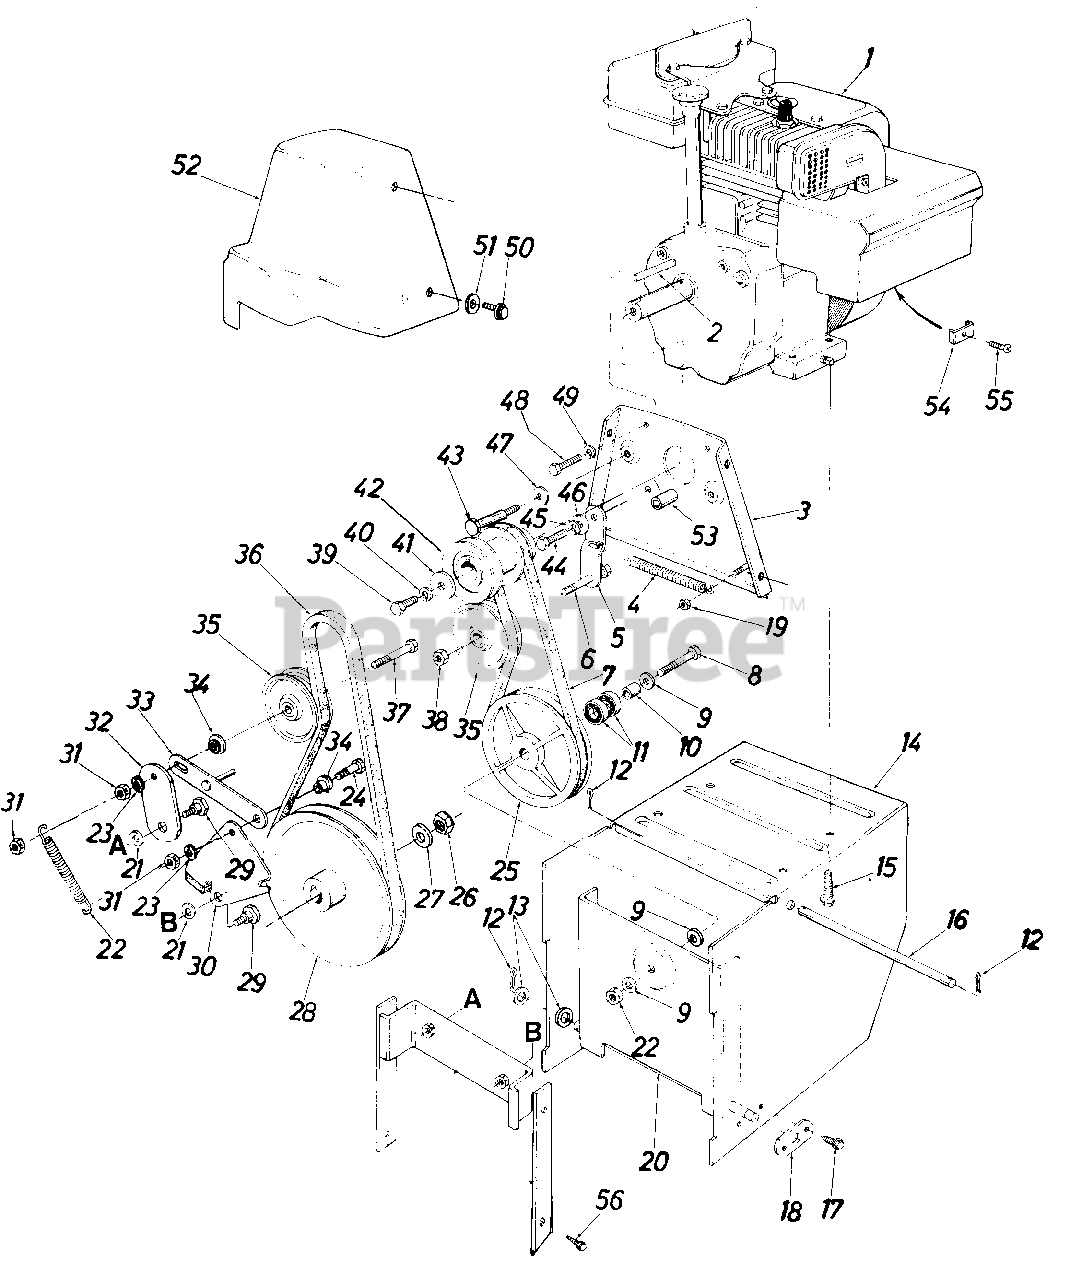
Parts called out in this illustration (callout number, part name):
1	Engine
2	Sq. Key 3/16" x 1.50" Lg.
3	Engine Plate Ass'y.
4	Extension Spring .50" O.D. x 3.97" Lg.
5	Drive Clutch Idler Brkt.
6	Hex Bolt 3/8-24 x 1.25" Lg.
7	V-Belt 3/8" x 29.0" Lg.
8	Hex Bolt 3/8-24 x 1.50" Lg.
9	Bell-Wash. .40" I.D. x .88" O.D. x .06
10	Spacer .38" I.D. x .62" O.D. x.75" Lg.
11	Ball Brg. .62" I.D. x 1.38" O.D. x .44
12	Cotter Pin 3/32" Dia. x .75" Lg.
13	Fl-Wash. .53" I.D. x 1.00" O.D. x .125
14	Frame Ass'y.
15	Hex Wash. Hd. Self-Tap Scr. 3/8-16 x 1.25" Lg.
16	Shaft .50" Dia. x 9.50" Lg.
17	Hex Wash. Hd. Self-Tap Scr. 1/4-20 x .50" Lg.
18	Axle Bracket
19	Hex L-Nut 1/4-20 Thd.
20	Drive Pulley Support Brkt. Ass'y.
21	Bell-Wash. .40" I.D. x 1.13" O.D.
22	Extension Spring .50" O.D. x 3.97" Lg.
23	L-Wash. 3/8" I.D.
24	Hex Scr. 3/8-16 x 1.25" Lg.
25	6.00" O.D. Drive Pulley Ass'y.
26	Hex Jam Cent. L-Nut 5/8-18 Thd.
27	Fl-Wash. .64" I.D. x .94" O.D. x .06
28	5/8" V-Pulley .628" I.D. x 7.50" O.D.
29	Shld. Bolt .625" Dia. x .170" Lg.
30	Brake Bracket Ass'y.
31	Hex Ins. L-Nut 3/8-16 Thd.
32	Auger Clutch Idler Brkt.
33	Brake Linkage Ass'y.
34	Shld. Spacer.625" I.D.
35	Flat Idler 2.25" O.D.
36	"V"-Belt 1/2 " X 38.7" Lg.
37	Hex Bolt 3/8-16 x 2.25" Lg.
38	Hex Ins. Jam L-Nut 3/8-24 Thd.
39	Hex Bolt 3/8-24 x 1.50" Lg.
40	L-Wash. 3/8" I.D.
41	Fl-Wash. .40" I.D. x 1.25" O.D.
42	Double Groove Engine Pulley
43	Shld. Scr. .498" x 3.0" Lg.
44	Hex Bolt 5/16-24 x 1.00" Lg.
45	L-Wash. 5/16" I.D.
46	Shld. Spacer.320" I.D.
47	Bell-Wash. .40" I.D. x .88" x .06
48	Hex Bolt 5/16-24 x .62" Lg.
49	L-Wash. 5/16" I.D.
50	Hex Wash. Hd. Self-Tap Scr. 1/4-20 X .50" Lg.
51	Fl-Wash. .28" I.D. x .75" O.D. x .06
52	Belt Cover
53	Spacer
54	Throttle Control Wire Clamp
55	Hex Sems Scr. #10-32 x .62" Lg.
56	Hex Wash. Hd. Self-Tap Scr. 3/8-16 x .75" Lg.
